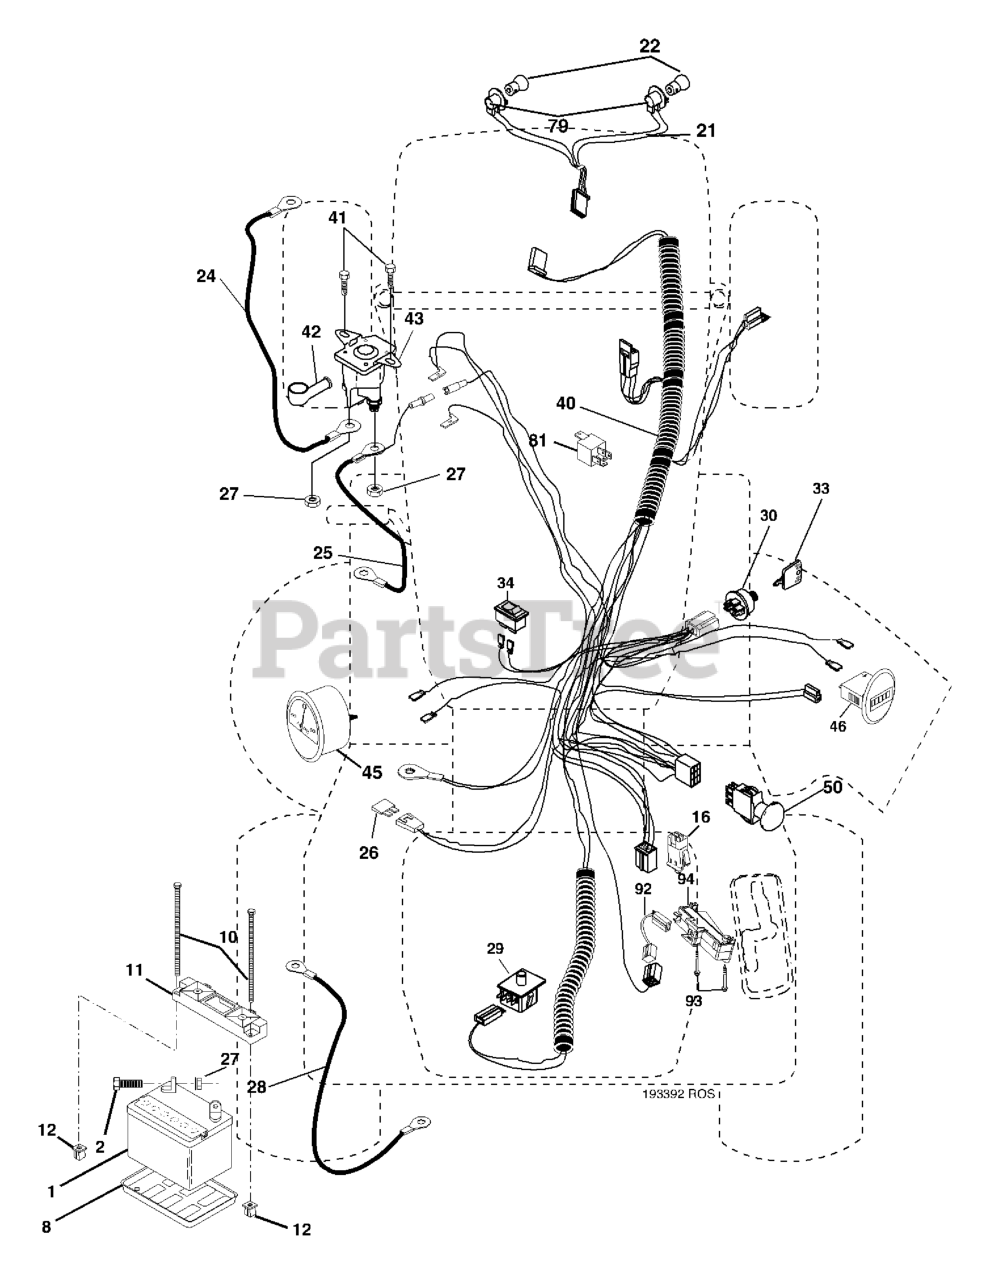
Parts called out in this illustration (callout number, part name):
1	BATTERY 12V .35 AMP
2	BOLT.HEX.1/4.X.3/4.DICHROMATE
8	BATTERY TRAY T
10	BOLT 1/4-20 X 7.5
11	BATTERY HOLDDOWN FRONT MOUNT
12	NUT, PUSH NYLON 1/4" BATTERY
16	SWITCH INTERLOOK PUSH-IN
21	HARNESS.W/LIGHT SOCKET
24	CABLE, BATTERY
25	CABLE.STARTER.6GA.22"RED
27	NUT
28	CABLE, GROUND
29	SWITCH.SEAT.DP W/RAMPS
30	SWITCH.IGN.DELTA.W.LGH.ROS
33	KEY MLD GEN DELTA
40	HARNESS. IGN.VGT.RHD
41	SCREW
42	TERMINAL COVER
43	SOLENOID
45	RP AMMETER.ROUND.SILVER.DELTA
46	RP HOURMETER SNAP-IN
50	RP.SWTICH.PTO.8.TERMINAL
79	BULB HOLDER ASM.
92	HARNESS.PIGTAIL.REVERSE.SWITCH
93	SCREW.PLASTITE
94	MODULE.REVERSE.ROS
